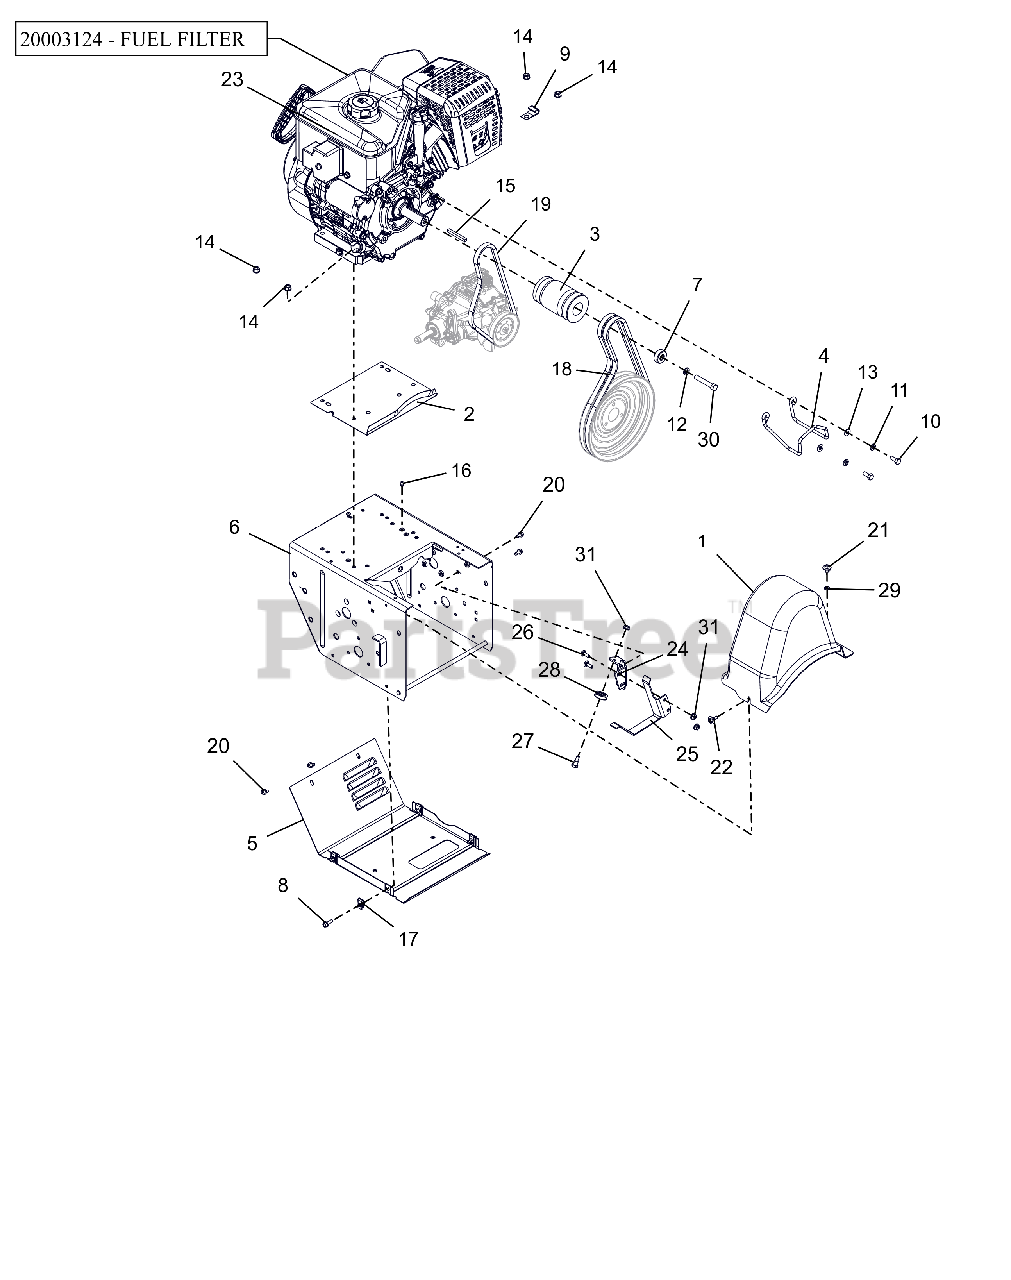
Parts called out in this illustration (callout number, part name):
1	COVER, BELT-LARGE
2	BAFFLE, WATER - LARGE BLOCK
3	SHEAVE, COMBO HYDRO WHEEL 4L
4	FINGER, BELT
5	COVER, BOTTOM - VENTILATED
6	FRAME, MAIN - PRO (WELDMENT)
7	BSHG-SPACER .47X1.25X.50
8	BLT, HWH .25-20X.75 G5 ZCC
9	J-CLAMP
10	BLT, HEX .31-24X.750 G5 ZCC
11	WSHR, LK-HVY .312X.097 ZCC
12	WSHR,LK-REG .375X.094 ZCC
13	WSHR,FLT .344X.688X.065 ZCC
14	NUT,LK-CTR-FLG .31-18 GF ZCC
15	KEY .25X.25X2.25
16	RVT, POP .1875 ZCC
17	NUT-RTNR .25-20X.56
18	V-BELT, HA-RAW EDGE (SET)
19	V-BELT, 4L-WRAPPED
20	SCR-TAP .25-20X.50 HWH ZCC
21	SCR, TAP .25-20X.50 LG HWH ZCC
22	SCR-TAP .25-20X.5 CAPTIVE
23	ENGINE,EFI420 GEN3 120V/60W
23	FILTER, FUEL - IN-LINE EFI
24	BRACKET, CLUTCH CABLE
25	FINGER, BELT - FLAT
26	BLT, RHSN .25-20X.750 G5 ZCC
27	BOLT, SHLDR -.375 X .375 X .25-20
28	PULLEY, CABLE
29	NUT-PUSH .25X.50 O.D.
30	BLT, HEX .38-24X2.25 G5 ZCC
31	NUT-LK-TOP-FLG .250-20 GF ZCC
